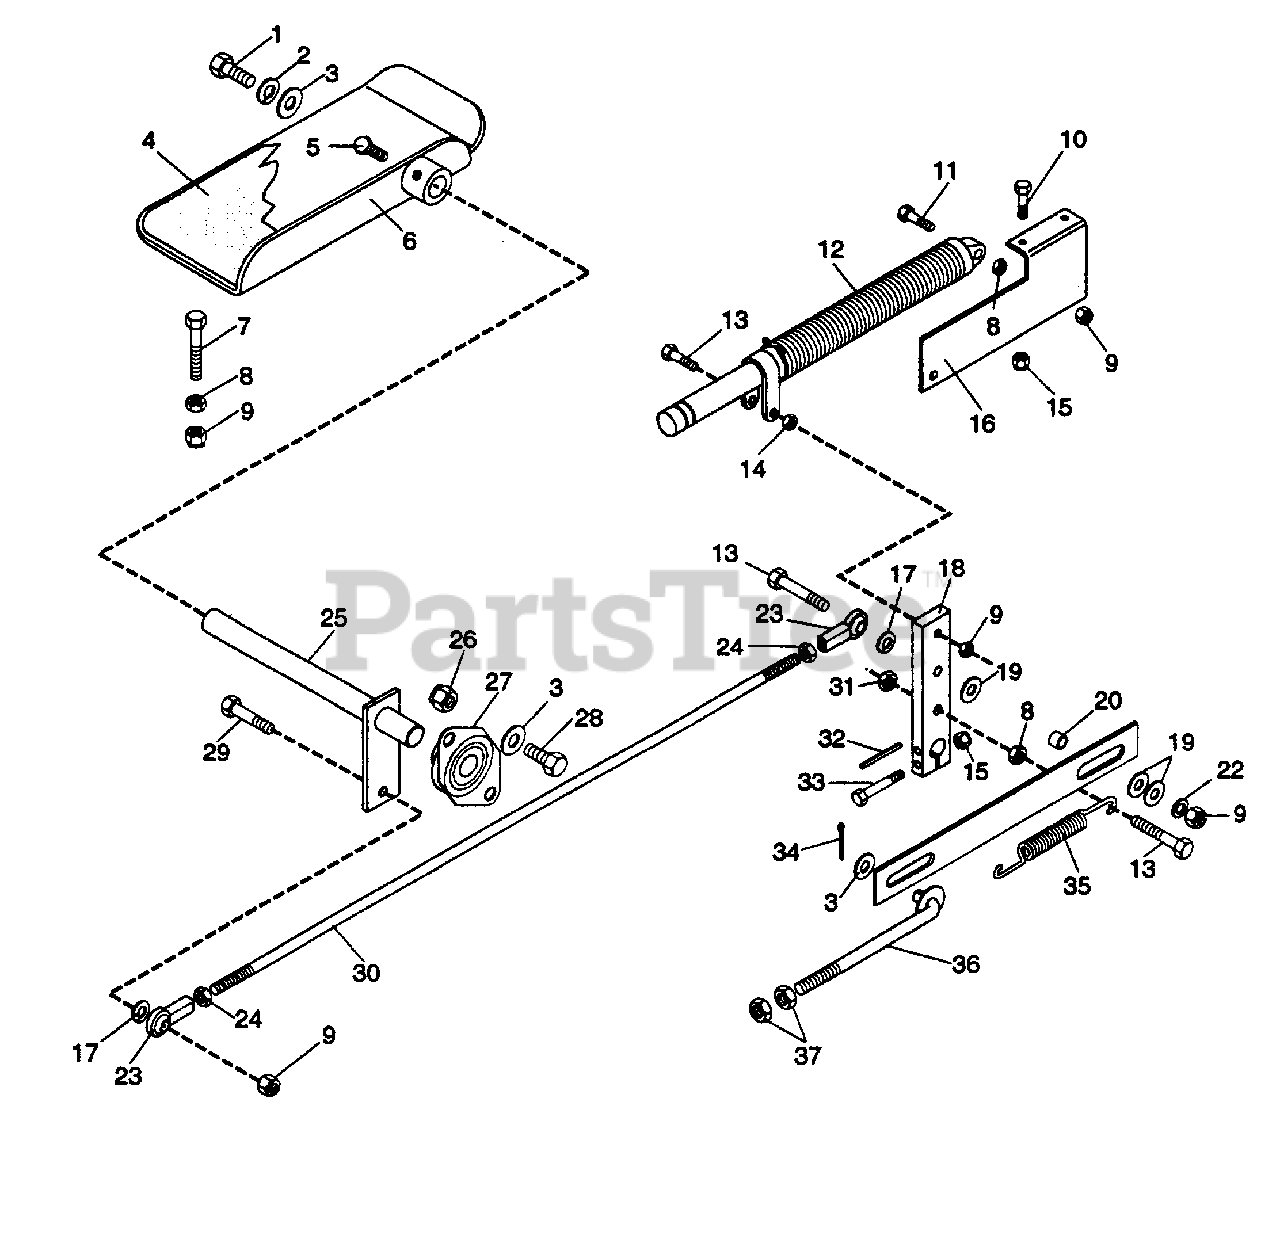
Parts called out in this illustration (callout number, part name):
1	BLT-HEX .38-16 X 1.00 PL GR 5
2	WSHR-LOCK .375 X .094 MED PL
3	WSHR-FL-STL .406 X .812 X .065 PL
4	CVR, LARGE FOOTBOARD
5	BLT-HEX .25-28 X .50
6	WLDMT, FOOT CONTROL LEVER
7	BLT-HEX .31-18 X 2.50
8	NUT-HEX .312-18
9	NUT-LK-NYL .312-18 PL
10	BLT-HEX .25-20 X .63
11	BLT-HEX .31-18 X 1.75 GR 5
13	BLT-HEX .31-18 X 2.00 PL GR 5
14	NUT-JAM .312-18 PL
15	NUT-LK-NYL .250-20 PL
16	BRKT, DAMPER
17	WSHR-LOCK .313 X .078 PL
18	ARM, PUMP
19	WSHR-FL-STL .531 X 1.062 X .095
20	BUSH., S .328 X .500 X .500 ST
21	STRP, NEUTRAL DETENT
22	WSHR-FL-STL .344 X .688 X .065
23	ROD END, 5/16 FEMALE
24	NUT-JAM .312-24 PL
25	WLDMT, CONTROL
26	NUT-LK-NYL .375-16 PL
27	BRG-FLG .75 X 2 HOLES X 2.123
28	BLT-HEX .38-16 X .75 PL GR 5
29	BLT-HEX .31-18 X 1.25 PL GR 5
30	ROD, SPEED CONTROL
31	NUT-LK-CTR .312-18 TYP N
32	PIN-SPRING .250 X 1.000
33	BLT-HEX .25-20 X 1.75 GR 2
34	PIN-COTR .09 X .75 PL
35	SG-TENS .091 X .500 X 5.500
36	WLDMT, DETENT ROD
37	NUT-HEX .375-24 ZC
